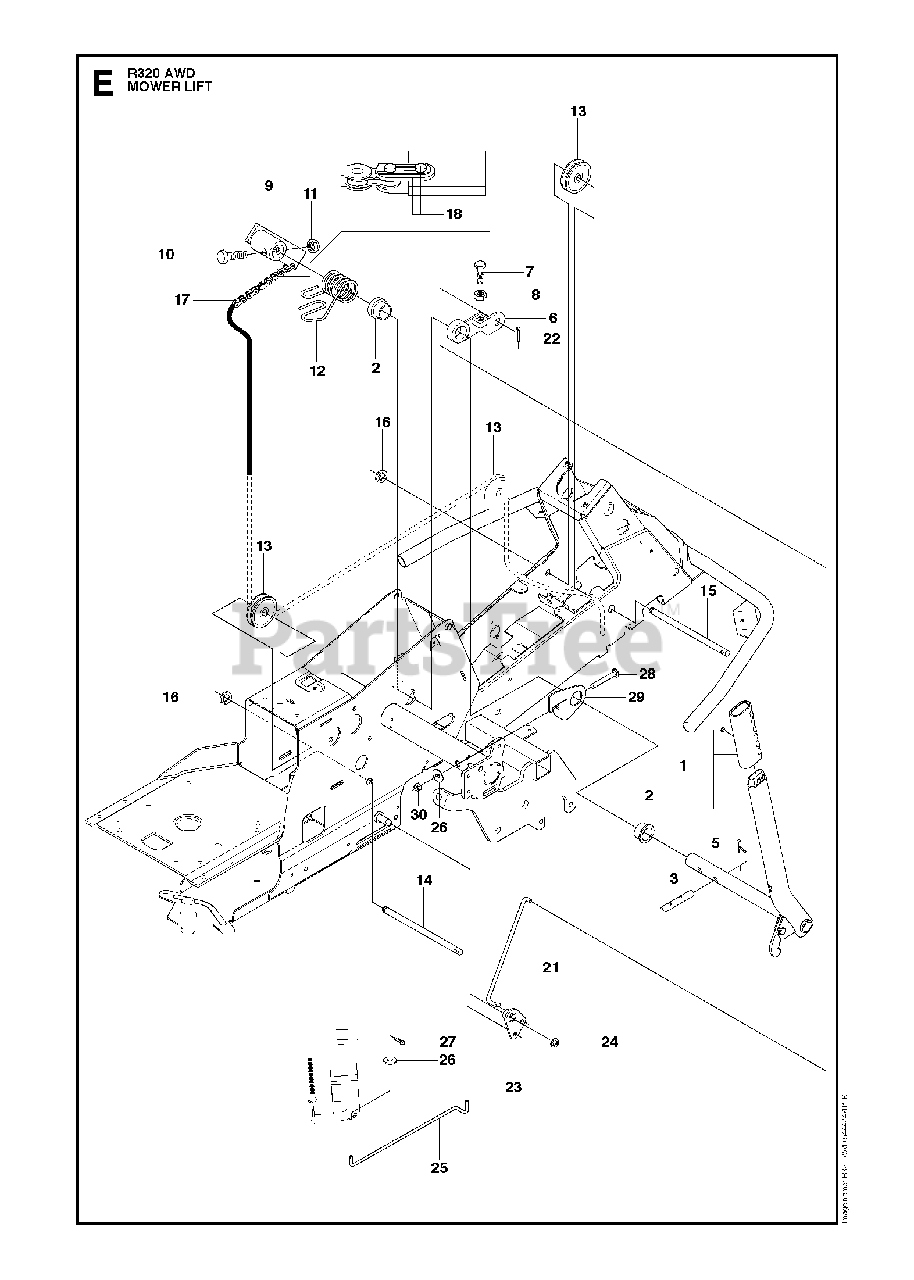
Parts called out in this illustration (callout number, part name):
1	LIFTING LEVER ASSY
2	BEARING FLANGE
6	LEVER CLUTCH
8	NUT
9	LIFTING ARM
11	Lock Nut, Fiber M12 DIN 985 Z/P
21	CONNECTION ROD
24	RETAINING RING
25	CONNECTION ROD
30	LOCKNUT M8
